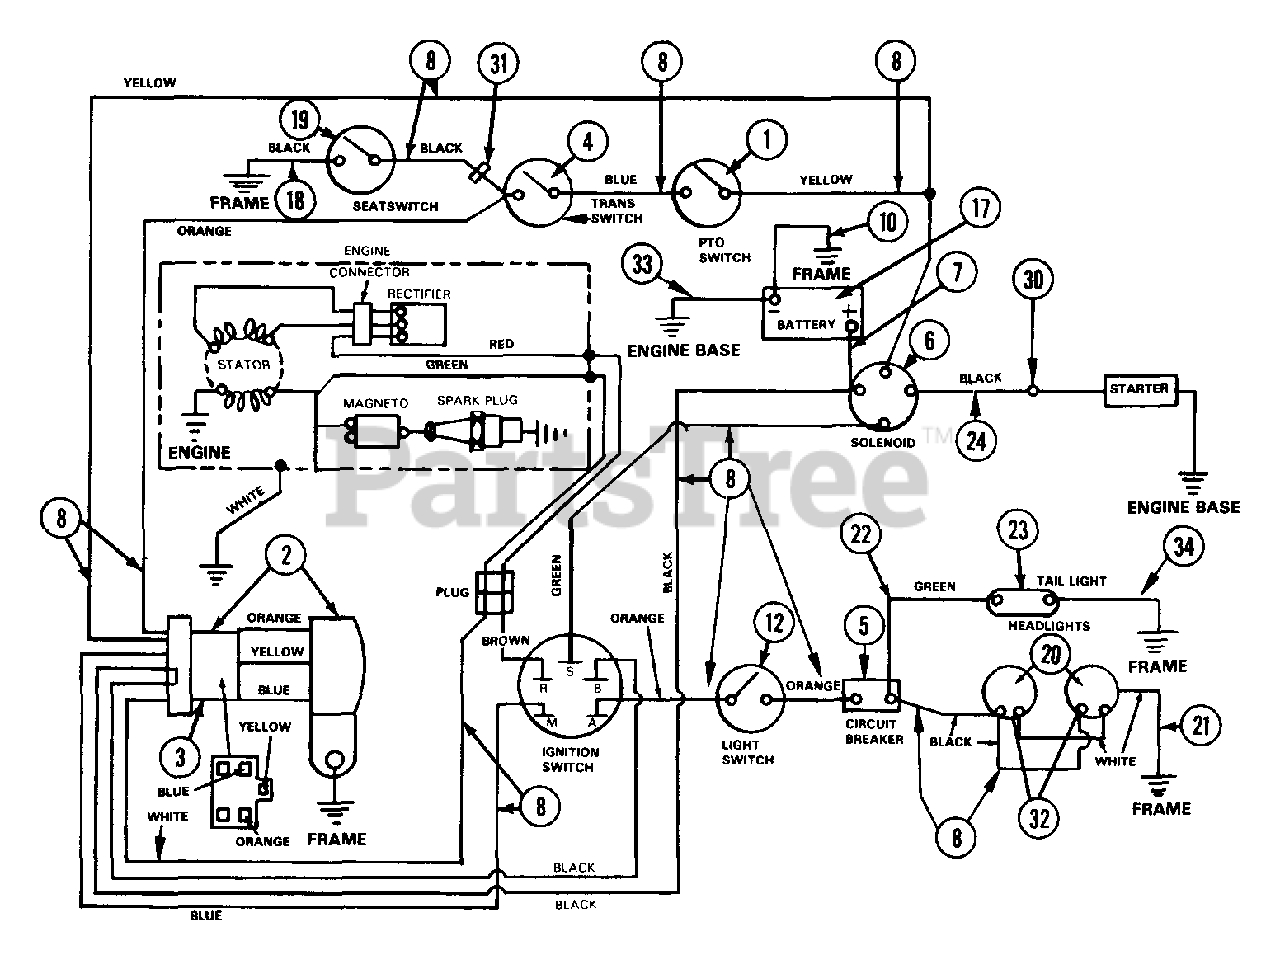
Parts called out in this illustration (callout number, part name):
1	SWITCH INTERLOCK
2	MODULE
3	CONNECTOR
4	SWITCH-NEUTRAL START N.O.
5	CIRCUIT BREAKER
6	SOLENOID
7	GROUND CABLE
8	WIRE HARNESS
10	GROUND CABLE
11	IGNITION SWITCH AND KEY ASSEMB
12	LIGHT SWITCH
17	BATTERY
18	GROUND WIRE
19	SWITCH SEAT
20	HEAD LIGHT
22	TAIL LIGHT WIRE
23	TAIL LIGHT
23	TAIL LIGHT LENS
24	GROUND CABLE
30	TIE DOWN
31	MUFFLER
32	CLAMP LOOP
33	GROUND CABLE .31X22.00X.31
34	GROUND WIRE
